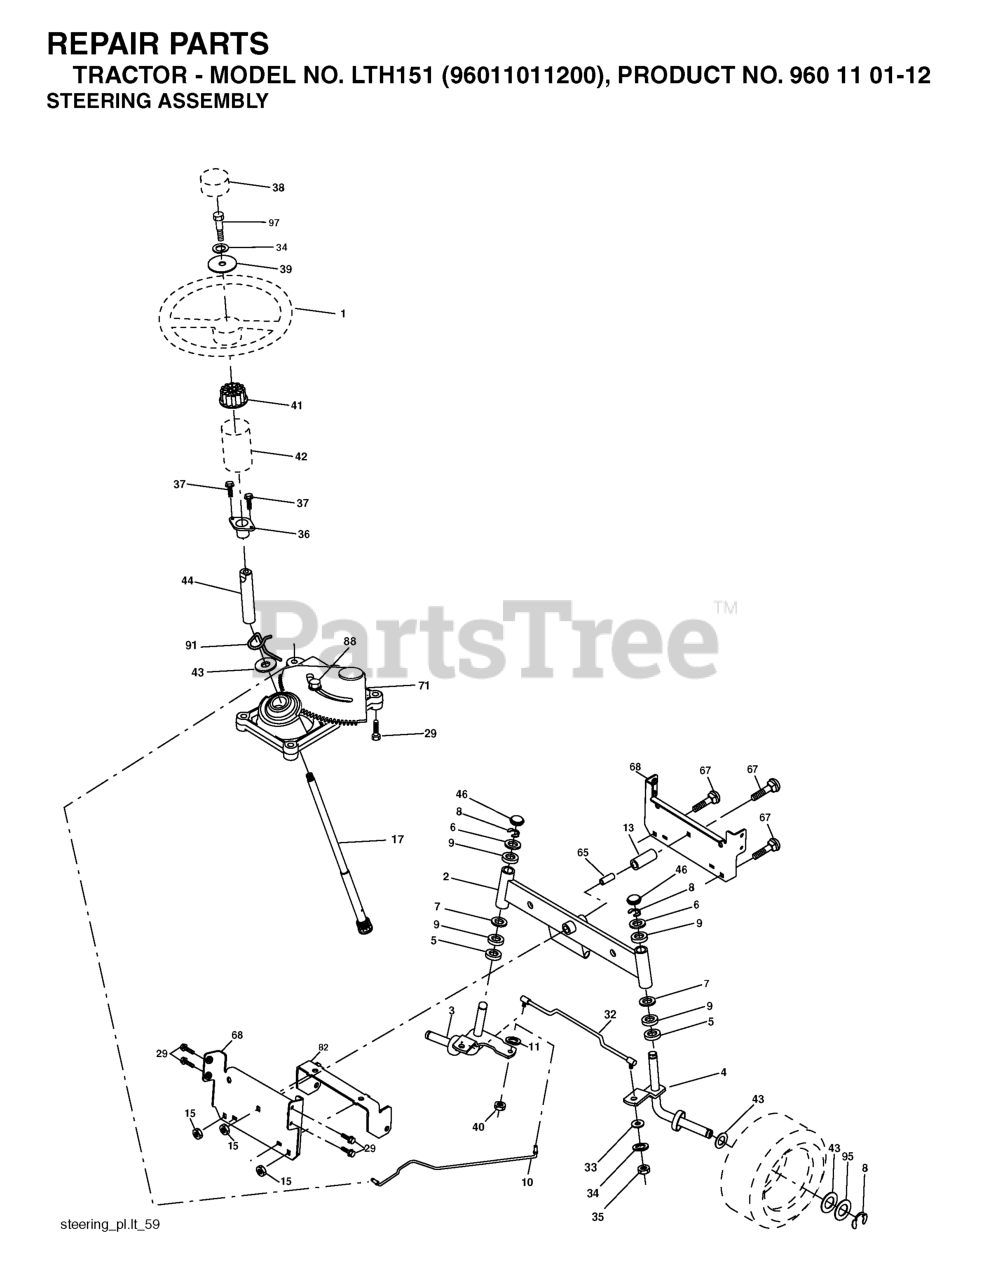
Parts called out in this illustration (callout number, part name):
1	STEERING WHEEL
2	AXLE.HALF.ASM.WELDED
3	SPINDLE.ASM.LH.15"TIRES
4	SPINDLE.ASM.RH.15"TIRES
5	THRUST WASHER
9	BRNG T
10	DRAGLINK.15".TIRES.2001
11	WASHER, LOCK 3/8
13	TUBE, PIVOT AXLE
15	NUT
17	SHAFT STEERING SPLINE
29	SCREW, 3/8-16X3/4
33	WASHER M
34	WASHER.LOCK.HVY.HLCL.SPR.5/16
35	NUT, CROWNLOCK
36	BUSHING, STEERING
37	SCREW.TT.#10-32X.5.3/8.FLANGE
38	INSERT.CAP.STRG.WH.GRAY
39	WASHER.11/32
40	NUT CROWNLOCK 3/8-24
41	ADAPTER, WHEEL STNG..
42	BOOT STEERING
44	SHAFT.EXTEN.STRG.SPLINE
46	CAP.SPINDLE.BLACK
65	SPACER BRACE AXLE
67	BOLT CARRIAGE
68	BRACE.AXLE.15"TIRES
71	STEERING ASM
82	BRACKET.SUSP.CHASSIS.FRONT.15
88	BOLT, SHOULDER 7/16-20
91	CLIP.STEERING
95	WASHER.HARDENED
